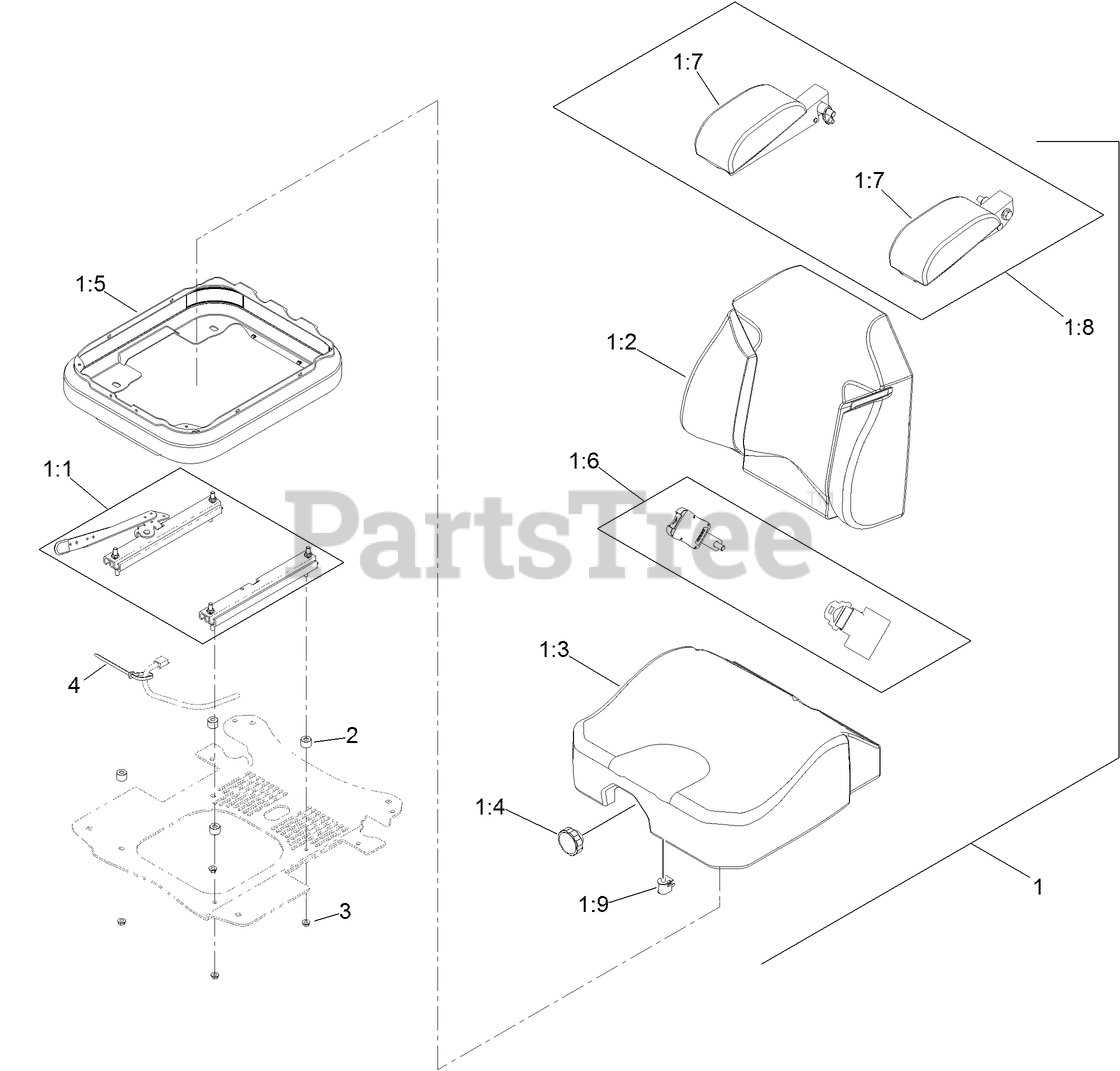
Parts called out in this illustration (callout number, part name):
1	SUSPENSION SEAT ASM
1:1	SEAT TRACK SET
1:2	COVER-BACK
1:3	COVER-CUSHION
1:4	Knob-Adjuster
1:5	Cover-Suspension Bellows
1:6	SEAT BELT KIT
1:7	ARM REST PAD SET
1:8	ARM REST SET
1:9	SWITCH-BAIL
2	SPACER
3	NUT-HF
4	TIE-PLASTIC
